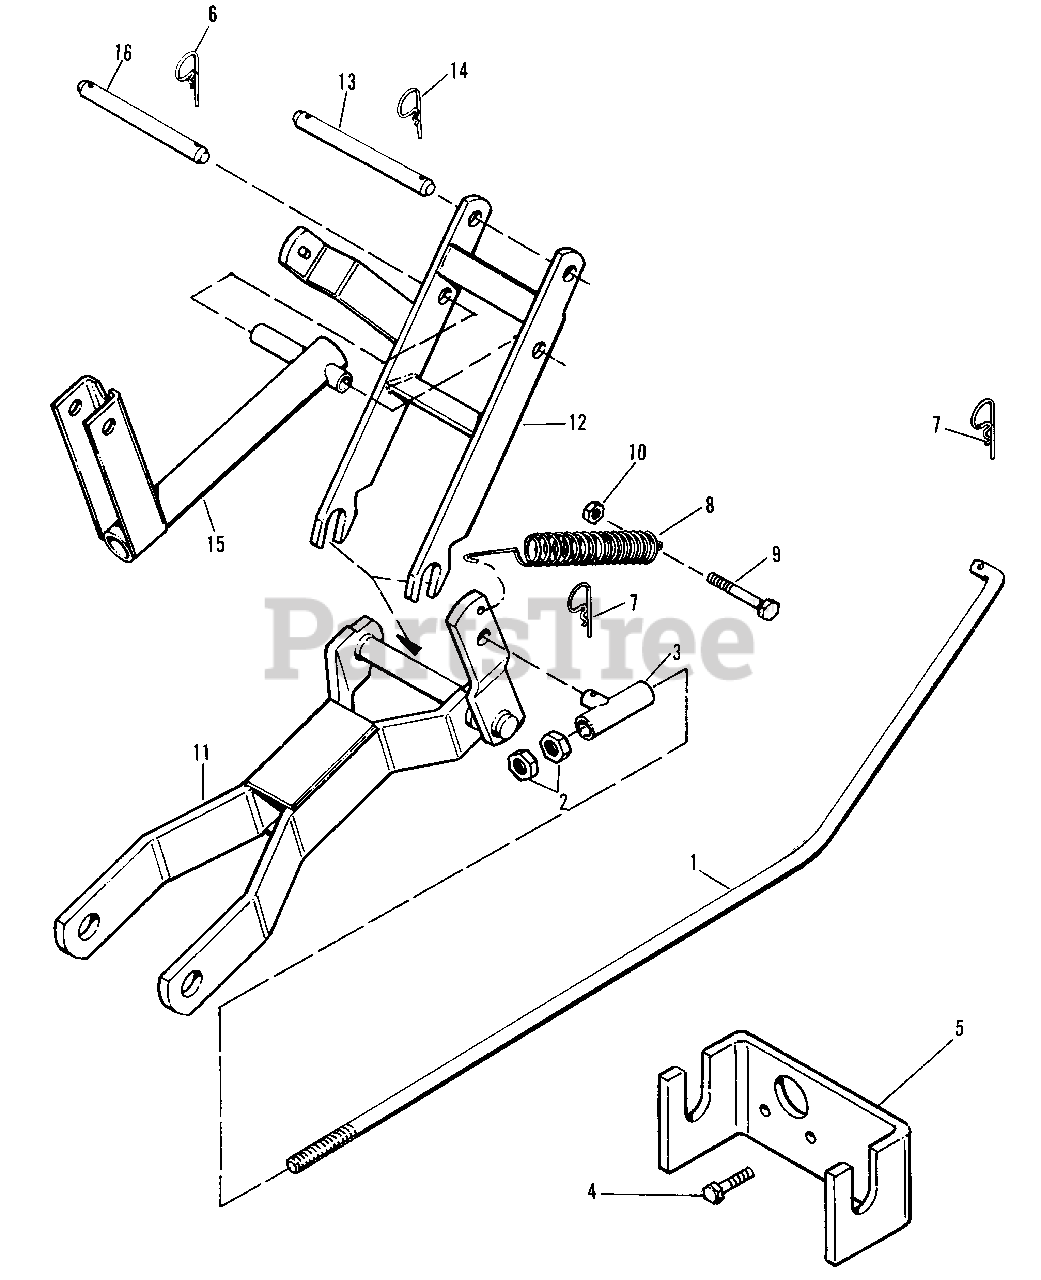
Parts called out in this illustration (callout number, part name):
1	LIFT ROD (Front)
2	NUT, Hex jam, 1/2-20
3	GUIDE TUBE ASSEMBLY
4	CAPSCREW, Hex, 3/8-16 x 1-1/4
6	CLIPS, Hairpin
7	CLIPS, Hairpin
9	CAPSCREW, hex, 3/8-16 x 2-1/2
10	NUT, hex, 3/8-16
11	HITCH & Lift ASSEMBLY
12	STRUT ASSEMBLY
14	CLIPS, Hairpin
